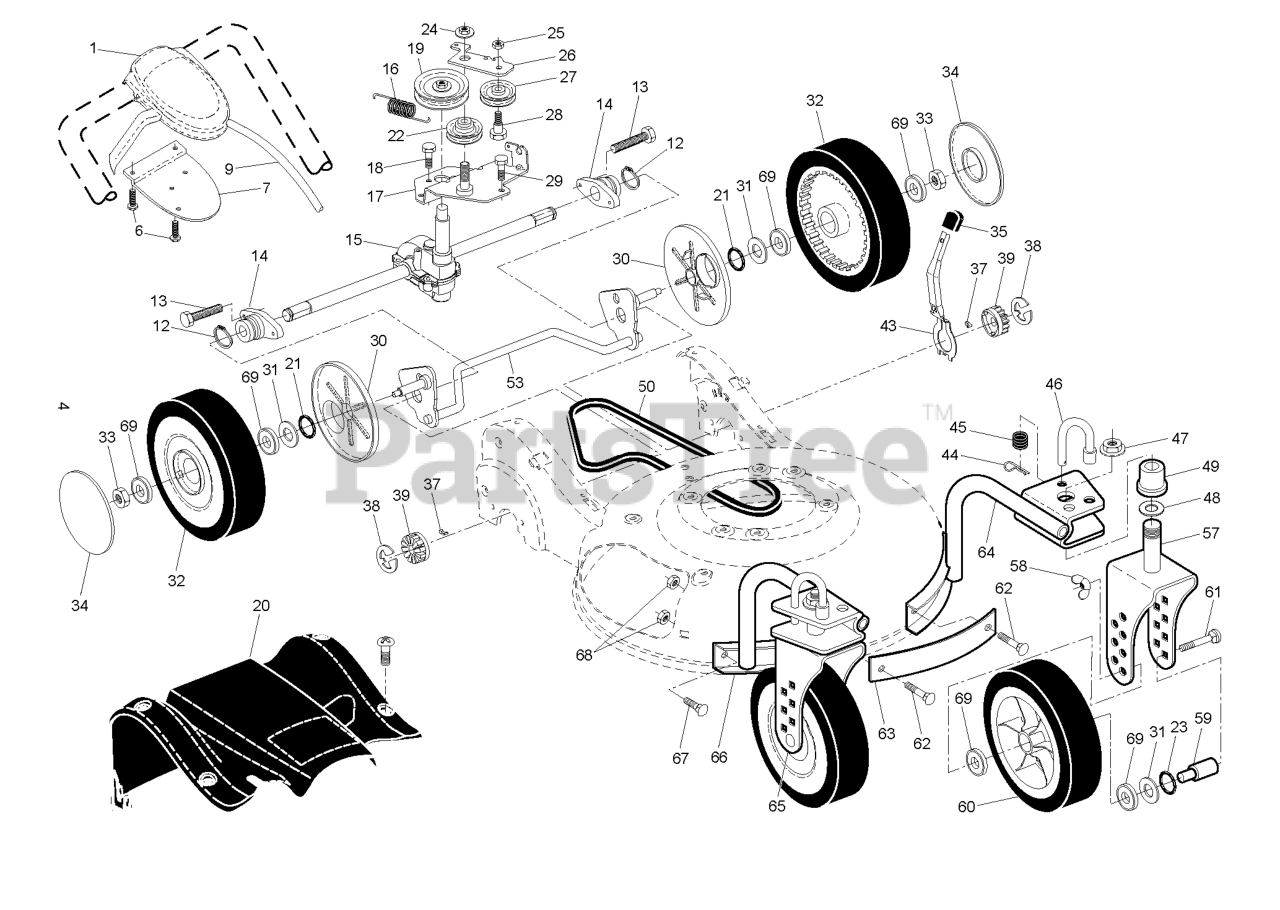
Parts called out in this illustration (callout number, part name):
1	Drive Control Assembly, Complete
6	SCREW, PHILLIPS HEAD 10 X 5/8
7	BRACKET.DRIVE.CONTROL.MOUNT.BL
8	ASM.CABLE.
12	RETAINING RING (2 2)(3 2)
13	SCREW.1/4-20X21/4.HEX.
14	BEARING / AXLE SUPPORT
15	TRANSMISSION.21.HV.RWGD.AW/EZ
17	BRACKET, GEAR CASE / DRIVE
19	RP PULLEY.DRIVE.EZ
20	COVER.DR.ASM.408006X418.CE
21	O-RING..070X.487.NEOPRENE
22	PULLEY.IDLER.V-BELT
23	O-RING
24	NUT.HEX.FLANGE.3/8-16.LOCKNUT
25	NUT.CENTERLOCK.5/16-
26	ARM.IDLER.BZP
27	IDLER PULLEY
28	SHOULDER BOLT
29	SCREW 14-20 X 5/8
30	DUST COVER, WHEEL
31	WASHER.FLAT.1/2
32	WHEEL.9X2.25.LP.TIGER.BLACK
33	NUT.HEX.FLANGE.3/8-16.LO(3 2)
34	HUBCAP.WHEEL.5.SPOKE.SILVER
35	KNOB.SELECTOR.SPRING.BLACK(3 2
37	PAWL, DRIVE
38	E-RING 7/16 RE
39	PINION.14.TEETH.FGD
43	LEVER, SELECTOR, HEIGHT, REAR
44	SPRING RETAINER
47	NUT.HEX.FLANGE.3/8-16.LOCKNUT
48	WASHER.FLAT.1/2
50	BELT, DRIVE
53	SHAFT.ASM.REAR.TORQUE.HV.BZP
57	BRACKET.WHEEL.ASM.LT.CASTER.OR
58	NUT.WING.5/16-18.YELLOW
60	WHEEL.9X2.25.LP.TIGER.SILVER
61	CARRIAGE BOLT
63	STRAP.FRONT.CASTER.ORANGE
64	SUPPORT.TUBE.ASM.LT
65	BRACKET.WHEEL.ASM.RIGHT.ORANGE
66	SUPPORT.TUBE.ASM.RT
68	NUT
69	BEARING.8".WHEEL
